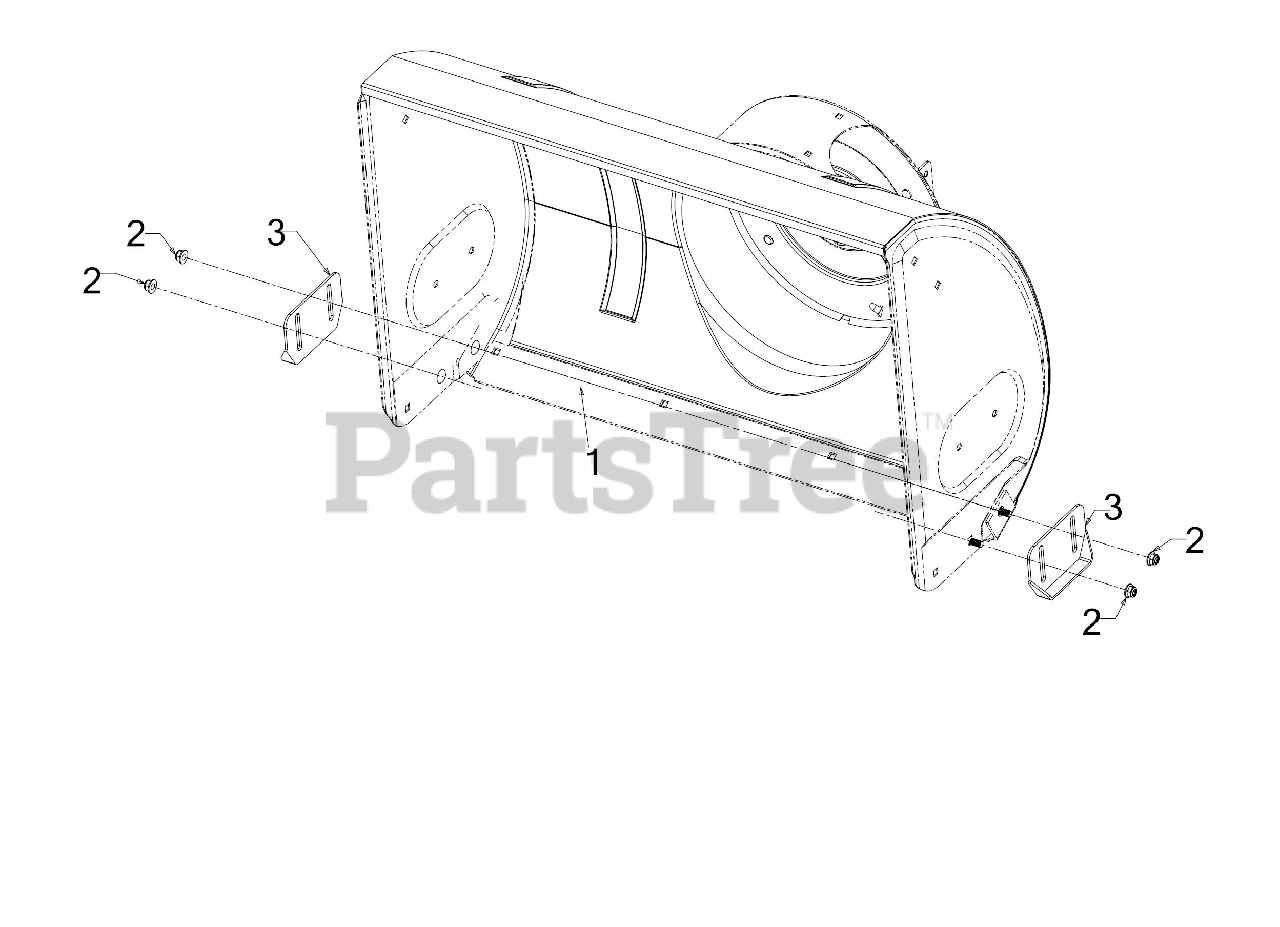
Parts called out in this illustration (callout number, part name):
1	CARRIAGE BOLT 5/16-18 x .75
2	FLANGE LOCK NUT 5/16-18
3	SLIDE SHOE
